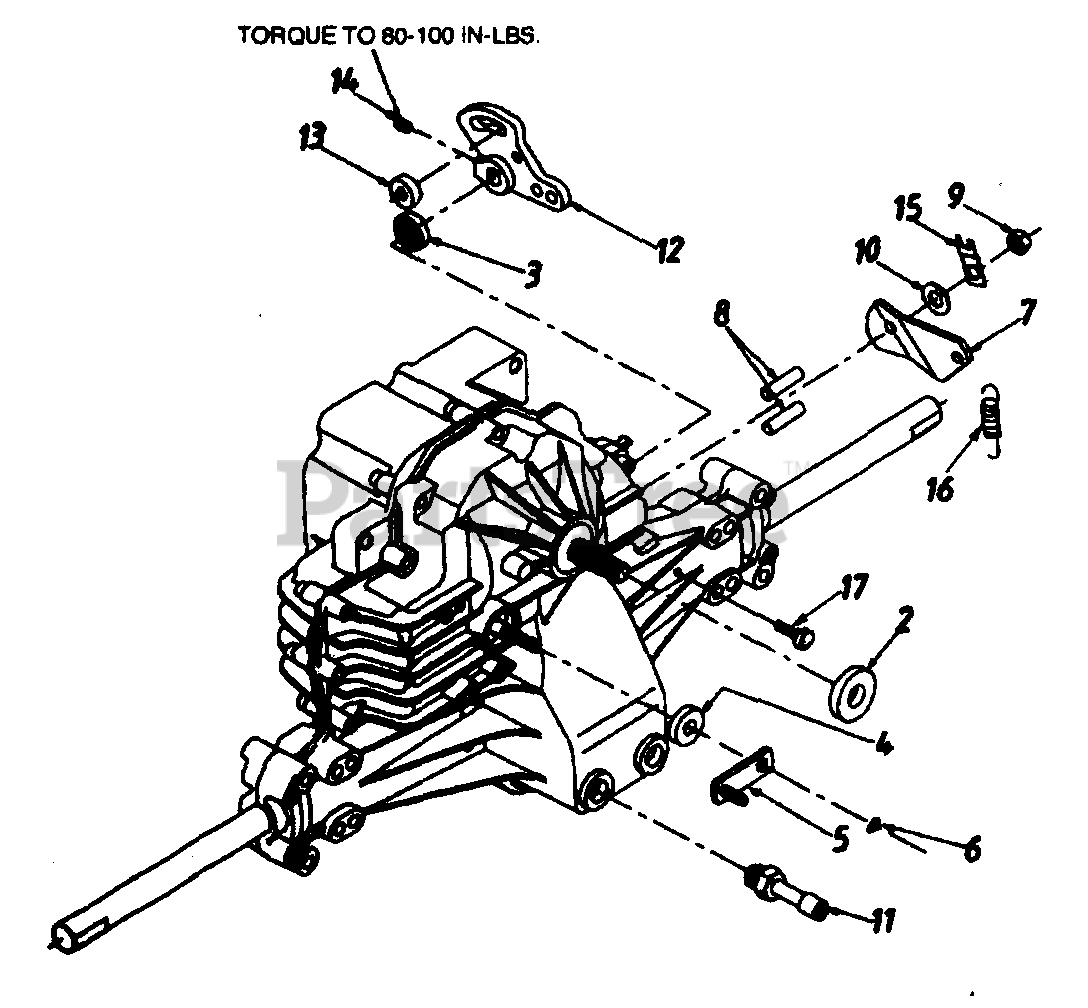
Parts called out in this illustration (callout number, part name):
4	Seal-Lip 10X25X7
5	Arm-Bypass
6	Ring-Retaining
7	Arm-Actuating
8	Pin-Actuating
9	Nut-Hex Lock 5/16-24
10	Washer 7/16" x 7/8" x.06"
11	Breather Ass'y.
12	Arm-Control
13	Puck-Dampener
14	Set Screw
15	Strap, Locking
16	Ext. Spring
17	Self Tapping Scr. #10-32
